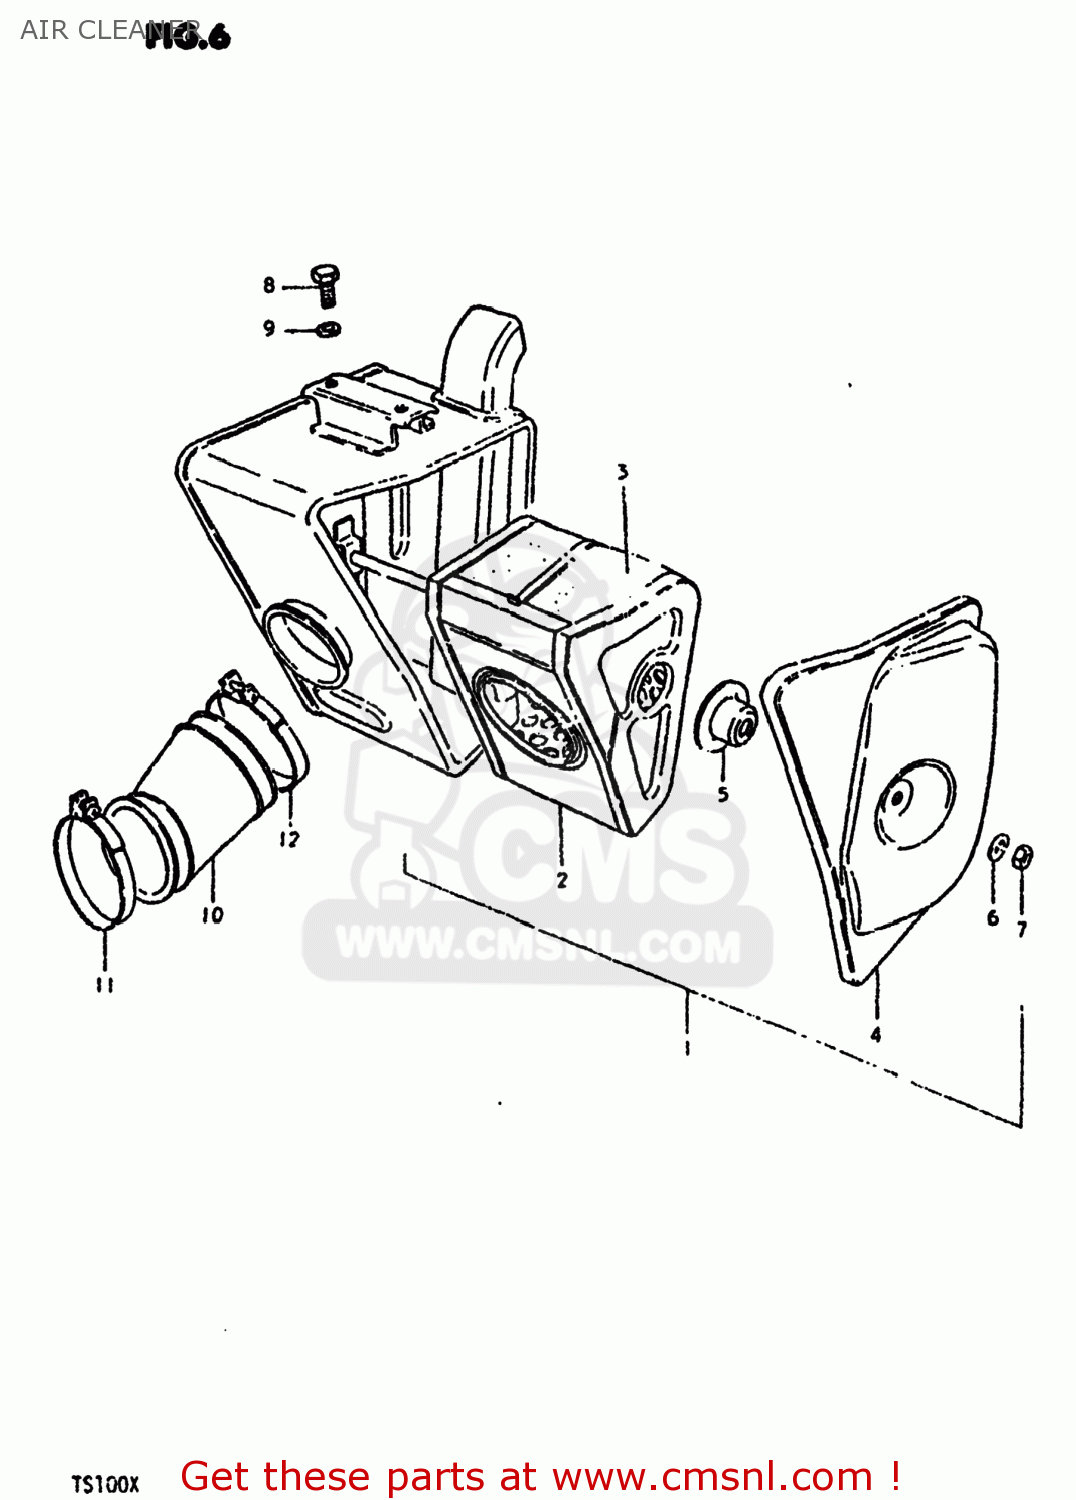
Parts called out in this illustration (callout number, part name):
1	CLEANER ASSEMBLY,AIR
2	FILTER ASSY,AIR CLEANER
3	FILTER
4	CAP
5	SPACER
6	WASHER
7	NUT
8	BOLT
9	WASHER
10	HOSE,CARBURETOR AIR INLET
11	CLAMP
12	CLAMP
